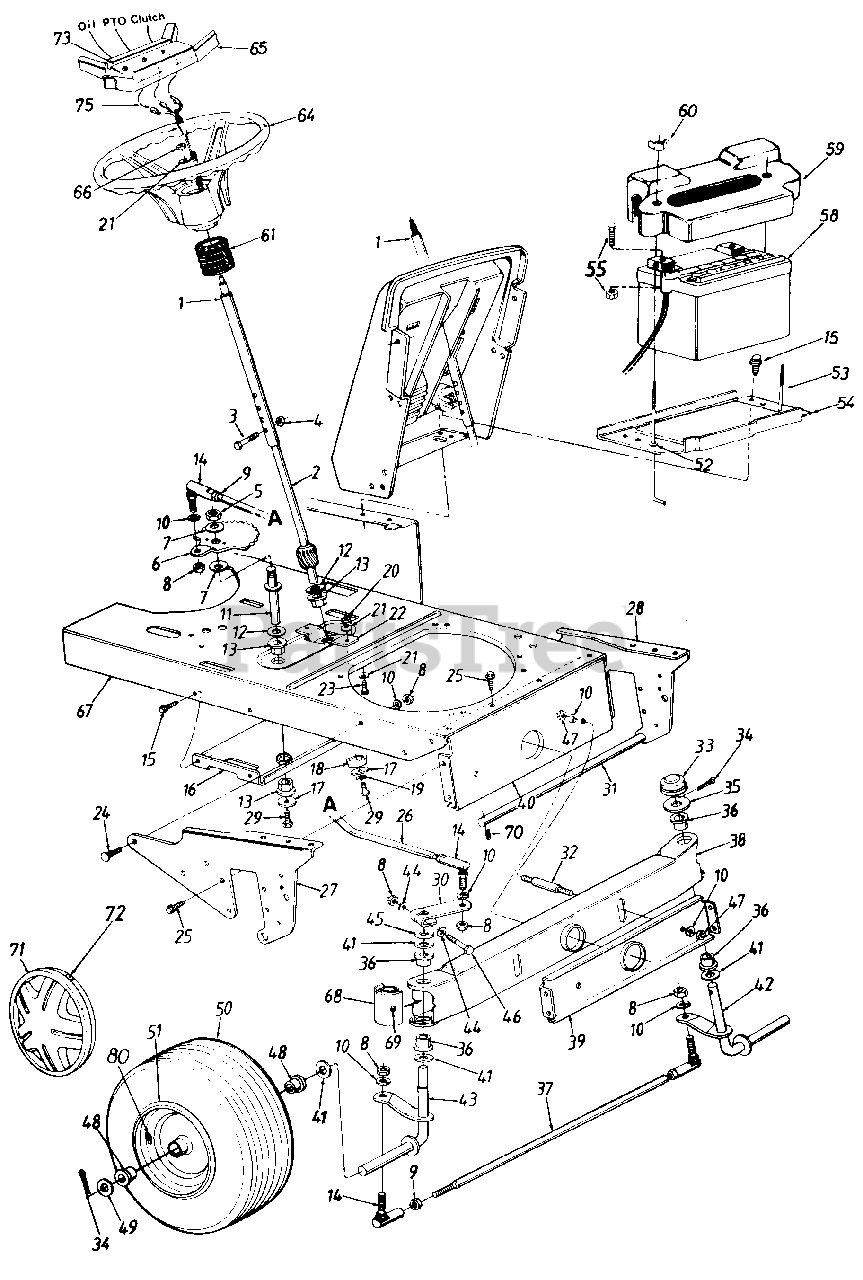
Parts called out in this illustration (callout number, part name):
1	Steering Column Ass'y.
2	Lower Steering Shaft
3	Hex Bolt 1/4-20 x 1.31" Lg.
4	Hex L-Nut 1/4-20 Thd.
5	Hex Nut 5/8-18 Thd.
6	Steering Gear Segment
7	Bell-Wash. 518" I.D. x 1.25" O.D.
8	Hex Nut 3/8-24 Thd.
9	Hex Jam Nut 3/8-24 Thd.
10	L-Wash. 3/8" I.D.
11	Steering Gear Segment Shaft
12	Fl-Wash. .64" I.D. x 1.24" O.D.
13	Hex Flange Brg. .63" I.D.
14	Ball Joint Ass'y.
15	Hex Wash. Hd. TT-Tap Scr. 1/4-20 x .5" Lg.
16	Deck Idler Support Brkt.
17	Fl-Wash. .33" I.D. x 1.25" O.D.
18	Spacer .985" I.D. x 1.25" O.D.
19	L-Wash. 5/16" I.D.
20	Hex Nut 5/16-24 Thd.
21	Bell-Wash. .345" I.D. x .88" O.D.
24	Ribbed Neck Bolt 3/8-24 x .8" Lg.
25	Hex Wash. TT-Tap Scr. 5/16-18 x .62" Lg.
26	Steering Drag Link
27	Pivot Bar Side Plate R.H.
28	Pivot Bar Side Plate L.H.
29	Hex Bolt 5/16-18 x .62" Lg.
30	Steering Arm
31	Deck Connecting Rod
32	Pivot Bar Shld. Bolt 3/8-16 x 518" Lg.
33	Cap
34	Cotter Pin 5/32" Dia.
35	Flat Washer
36	Flange Brg. .757" I.D.
37	Tie Rod 20.25" Lg.
38	Pivot Bar Assy.
41	Fl-Wash. .76" I.D. x 1.49 O.D.
42	Front Axle Ass'y. L.H.
43	Front Axle Ass'y. R.H.
44	Bowed Washer
45	Spacer .755" I.D. x 1.25" O.D.
46	Hex Bolt 3/8-24 x 2.25" Lg.
47	Hex Nut 3/8-16 Thd.
48	Needle Brg. .75" I.D.
49	Fl-Wash. .71" I.D. x 1.5" O.D.
50	Wheel Ass'y. Comp.
51	Rim Only
52	Push Nut
53	Battery Hold Down Rod
54	Battery Support Brkt.
55	Comes w/Battery
58	Battery (275 Cold Crank Amps)
59	Battery Cover
60	Wing Nut Plastic 1/4-20 Thd.
61	Steering Bellow
64	Steering Wheel
65	Steering Wheel Insert
66	Hex L-Nut 5/16-24 Thd.
67	Lower Frame
68	Pivot Bar End Cap
69	Grease Fitting
70	Internal Cotter Pin
71	Hub Cap
72	Spring Clip
73	Steering Wheel Insert Label
75	Bulb
80	Air Valve
